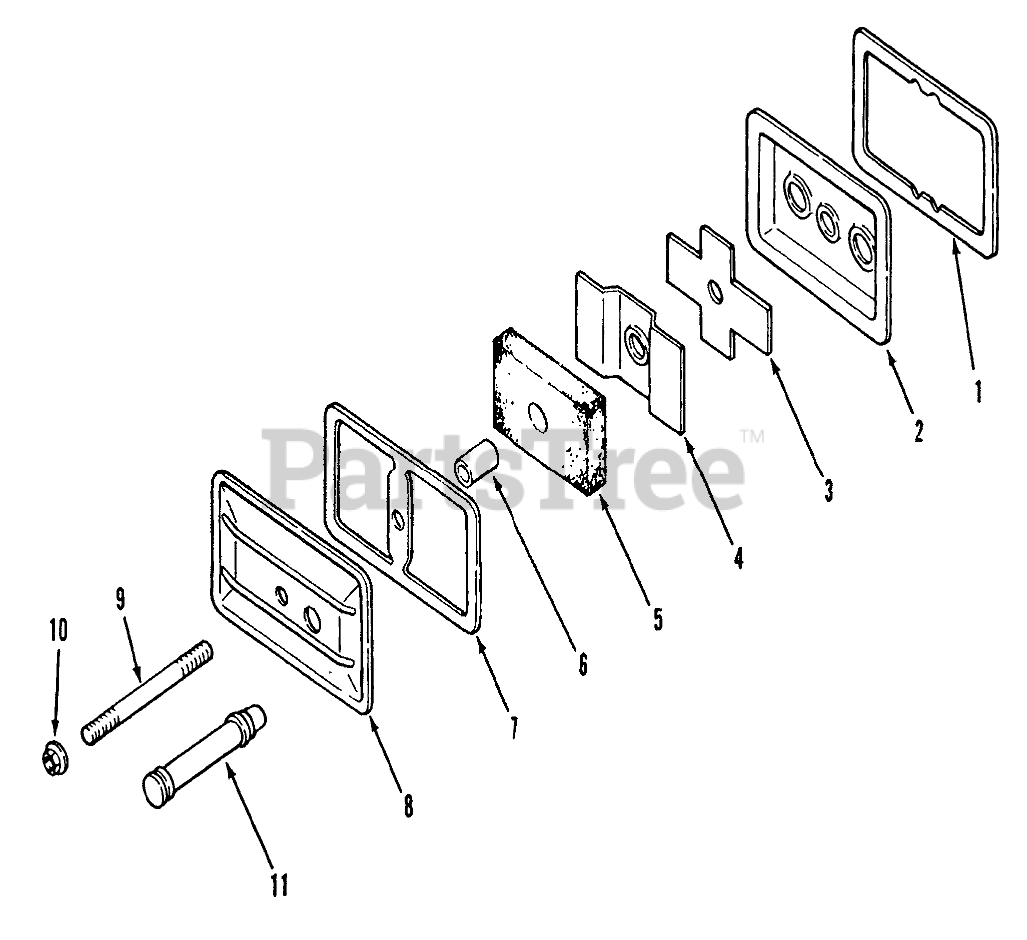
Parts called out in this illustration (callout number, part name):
1	Gasket
2	Plate
3	Reed
4	Baffle
5	Filter-Breather
6	Seal
7	Gasket
8	Cover-Breather Plate
9	Valve Cover Stud 1/4-20 x 3-1/4
10	Palnut
11	Hose-Breather
